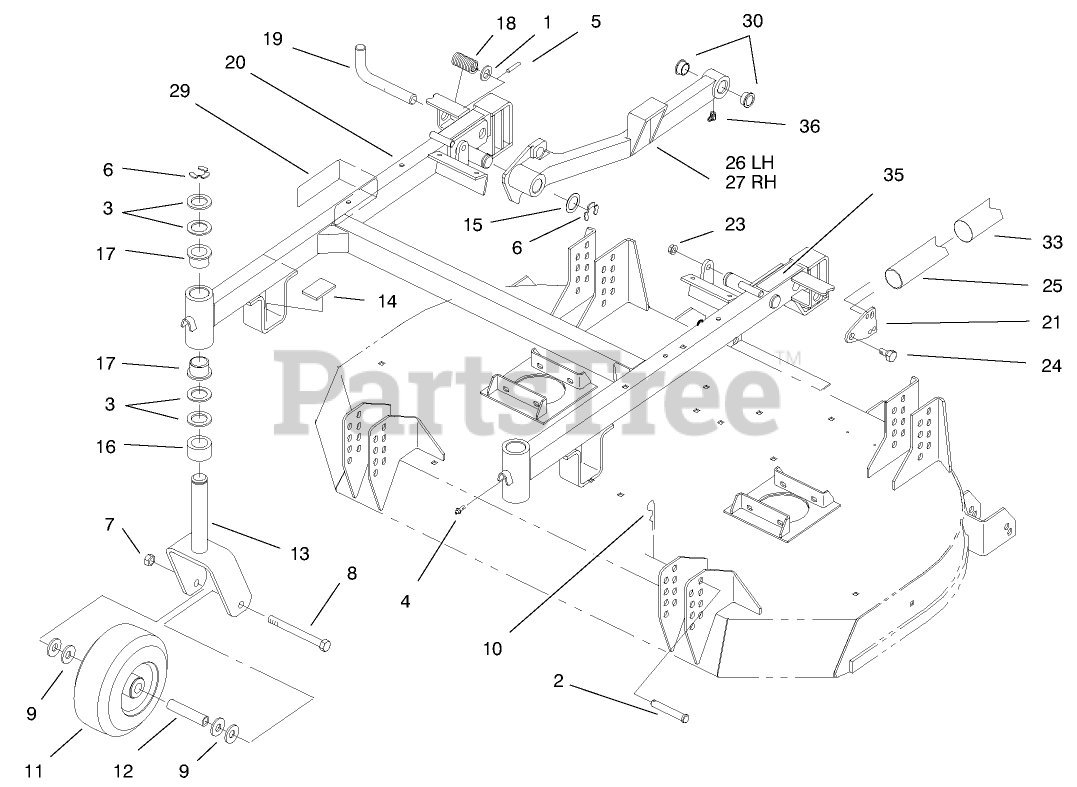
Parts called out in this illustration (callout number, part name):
1	WASHER
2	PIN-CLEVIS
3	WASHER-THRUST
4	FITTING-GREASE
5	PIN-ROLL
6	RING-RETAINING
7	NUT-HEX
8	SCREW-HH
9	WASHER-FLAT
10	PIN-HAIR
11	CASTOR WHEEL ASM
12	SPANNER-TIRE
13	Castor Fork
14	CUSHION - RUBBER
15	Washer
16	SPACER-CASTOR
17	BUSHING
18	SPRING-COMPRESSION
19	PIN - PIVOT
20	Frame-Carrier
21	PLATE-END, SPRING
23	NUT-LOCK, NI
24	BOLT-SHOULDER
25	SPRING-EXTENSION
26	Push Arm ASM LH
27	Push Arm ASM RH
29	DECAL - HOC
30	BEARING-FLANGE
33	COVER-SPRING
35	DECAL-WARNING
36	FITTING-GREASE
